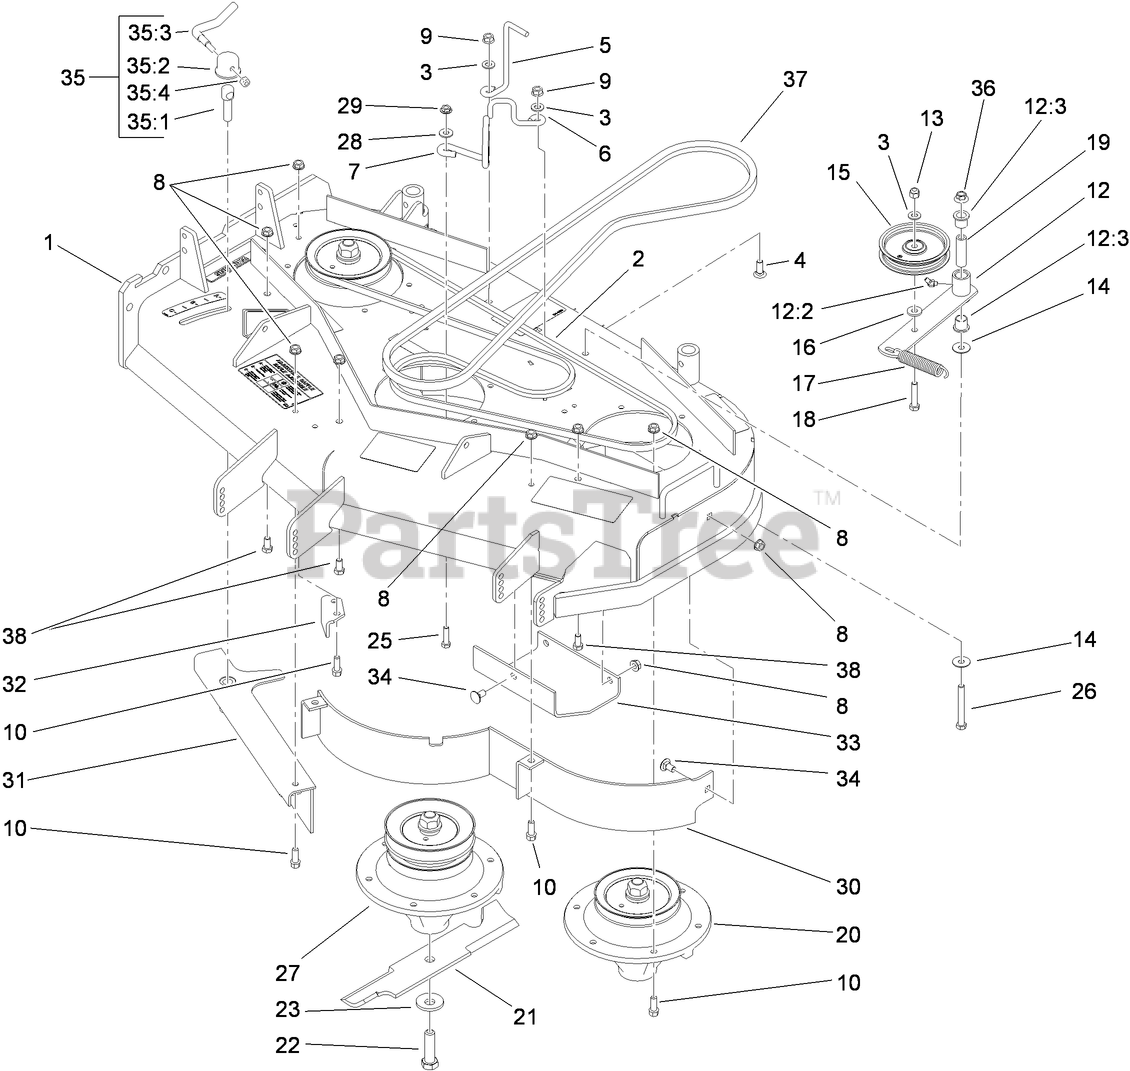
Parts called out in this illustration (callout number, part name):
1	DECK ASM
2	BELT-V
3	WASHER-FLAT
4	SCREW-CARR
5	GUIDE-BELT
6	GUIDE-BELT
7	GUIDE-BELT
8	NUT-HHF, WHIZ
9	NUT-HF
10	SCREW-HWH
12	IDLER ARM ASM
12:2	FITTING-LUBE, 45 DEG
12:3	BUSHING-FLANGE
13	NUT-LOCK, NI
14	WASHER
15	PULLEY-IDLER
16	WASHER-SPACER
17	SPRING-EXTENSION
18	SCREW-HH
19	SPACER
20	SPINDLE ASM
21	BLADE-14 INCH (HIGH SAIL)
22	SCREW-BLADE
23	Washer-Blade Bolt, Heavy
25	SCREW-HH
26	SCREW-HH
27	SPINDLE ASM
28	WASHER-FLAT
29	NUT-HF
30	BAFFLE ASM
31	ADJUST BAFFLE ASM
32	BAFFLE-DISCHARGE
33	PLATE-SKID
34	SCREW-CARR
35	LEVER ASM
35:1	Screw-Lock
35:2	CAP-LOCK
35:3	Lever-Lock
35:4	NUT-LOCK, NI
36	NUT-HF
37	BELT-V
38	SCREW-HH
